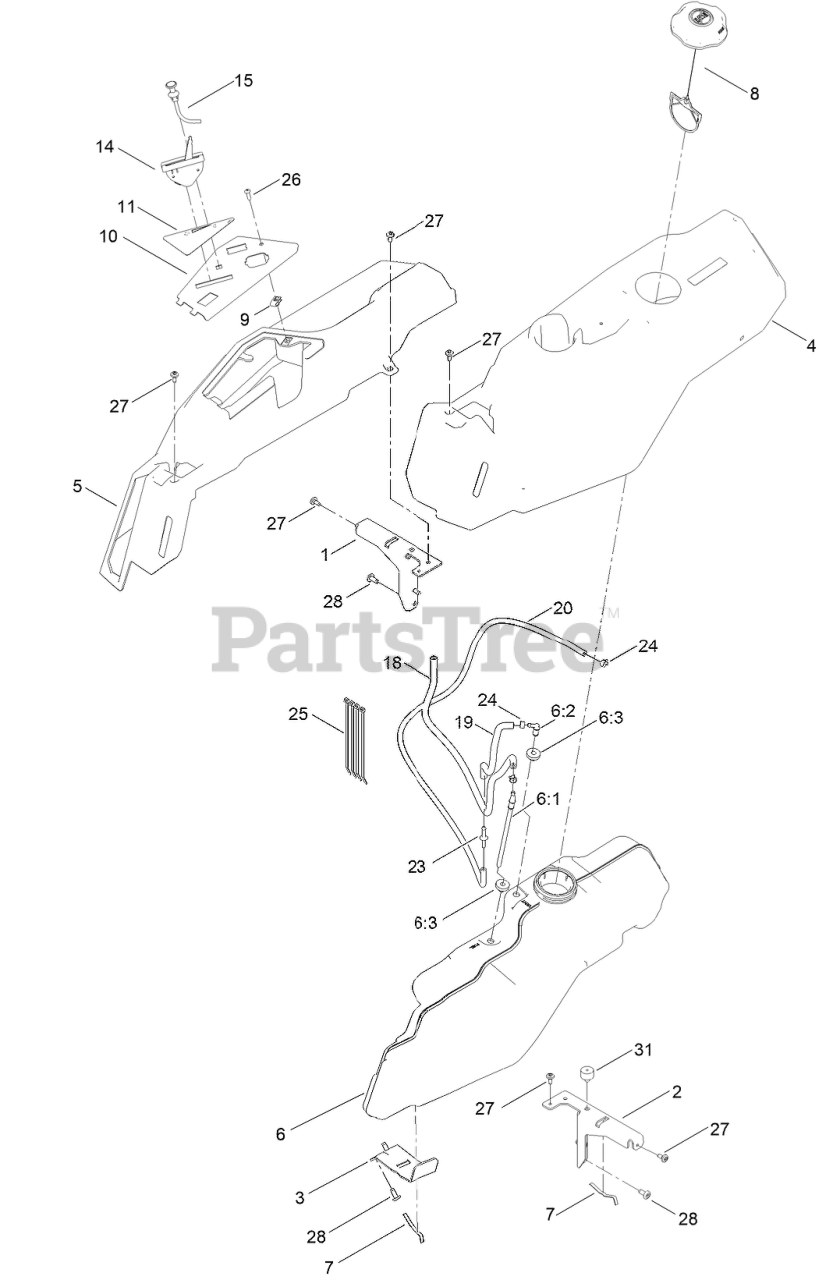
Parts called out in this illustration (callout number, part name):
1	SUPPORT-POD, RH
2	SUPPORT-POD, LH
3	SUPPORT-TANK, FUEL
4	POD-LH
5	POD-RH
6	FUEL TANK ASM
6:1	CONNECTOR-ELBOW, 90 DEG
6:2	FITTING-PLASTIC
6:3	BUSHING
7	SPRING
8	CAP-FUEL, RATCHETING
10	PANEL - CONTROL
11	DECAL-PANEL, CONTROL
14	CABLE-THROTTLE
15	CABLE-CHOKE
18	HOSE-FUEL
19	HOSE-FUEL
20	HOSE-FUEL
23	ADAPTOR-ORIFICE
24	CLAMP-HOSE
25	TIE-CABLE
26	SCREW-PRH
27	SCREW-SHOULDER
31	BUMPER-GROMMET
